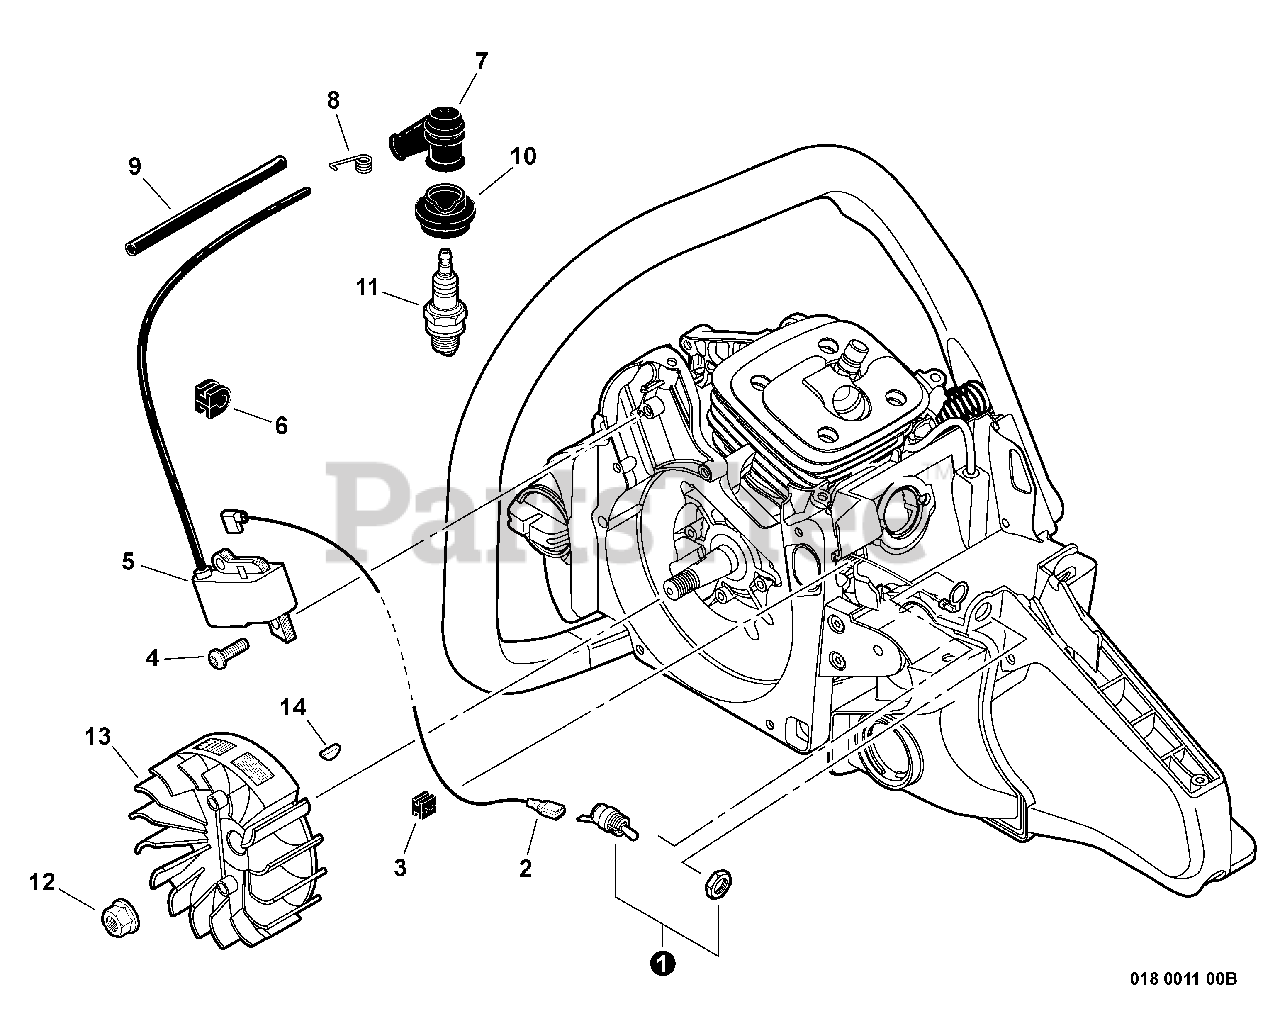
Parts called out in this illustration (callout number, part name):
1	IGNITION SWITCH KIT
2	LEAD - IGNITION
4	SCREW - 5X16
5	COIL, IGNITION
7	CAP, SPARK PLUG
8	TERMINAL, SPARK PLUG CAP
10	SEAL, SPARK PLUG
11	SPARK PLUG -- BPM-8Y
11	SPARK PLUG -- BPMR-8Y
12	NUT - 8 -- FLANGE
13	FLYWHEEL
